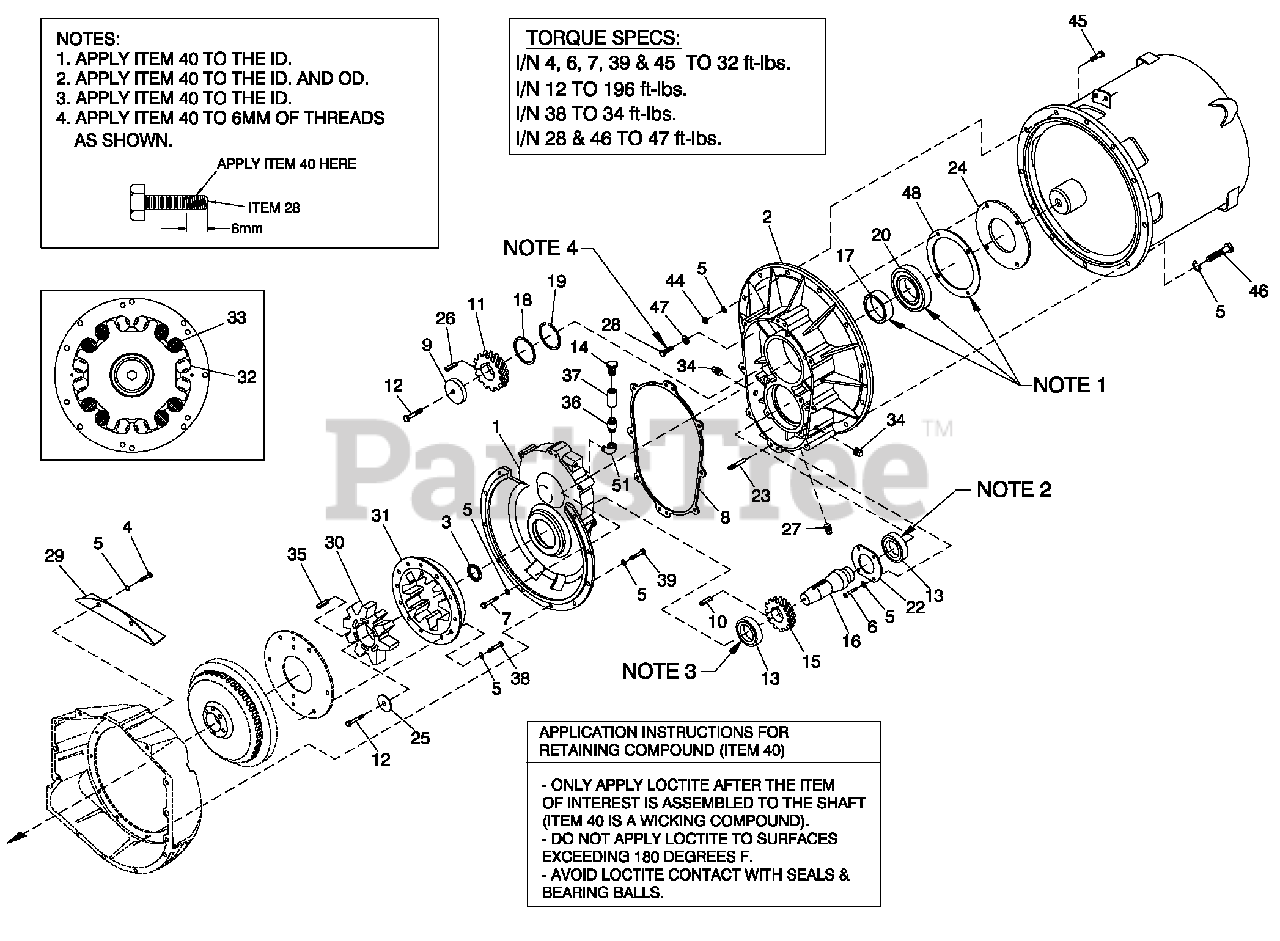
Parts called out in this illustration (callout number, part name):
1	GEAR CASE ENG. MACHINED
2	GEAR CASE ALT. MACHINED
3	SEALOIL
4	SCREW HHC M10l1.5X 20 G8.8
5	WASHER LOCK M10
6	S CREW HHC M10l1.5X 25 G8.8
7	S CREW HHC M10l1.5X 70 G8.8
8	GASKET 390 GEAR BOX
9	S PACER .69 X 2.75 X .37 ST/ZNC
10	KEY 1 0 X 1 6 X 4 6
11	GEAR OUTPUT 1.65:1
12	SCREW HHC M16-2.0X 35 G10.9
13	BALLBRG65X 120X23
14	BREATHER
15	GEAR INPUT 1.65:1
16	SHAFT 390 INPUT GEAR
17	COLLAR HARDENED
18	SEALOIL
19	SNAP RING INT 120MM
20	BEARING #6213 SEALED
22	PLATE INTRNLBRG RET
23	PIN DOWEL M8X 24
24	PLATE BEARING THRST
25	SPACER STRESSPROOF
26	KEY 1 0 X 1 6 X 4 0
27	PLUG PIPE 3/8"MAGNETIC
28	SCREW HHFC M10-1.5X 25 G10.9
29	COVER GEARBOX GUARD
30	COUPLING INNER DRAWN
31	COUPLING OUTER MACHN
32	DAMPER GB CPLRVIBRA
33	DAMPER GB CPLRVIBRA
34	PLUG STD PIPE 3/8 STEEL SQ HD
35	KEY 1 0 X 1 6 X 5 0
36	NIPPLE PIPE3/8NPTX 3-1/2
37	COUPLING FULL 3/8-18
38	SCREW HHC 3/8-16 X1-1/2G8
39	SCREW HHC M10l1 .5X 25 G8.8
40	RETAINING COMPOUND
44	NUTHEXM10-1.5G8 YEL CHR
45	SCREW HHC M10l1 .5X 60 G8.8
46	SCREW HHC M10l1 .5X 40 G10.9
47	WAS HER FLAT M10 S EALING COPPER
48	GASKET SEAL PLATE 390 G B
50	THREADLOCK AND SEALANT
51	ELB OW 90DSTREET3/8
